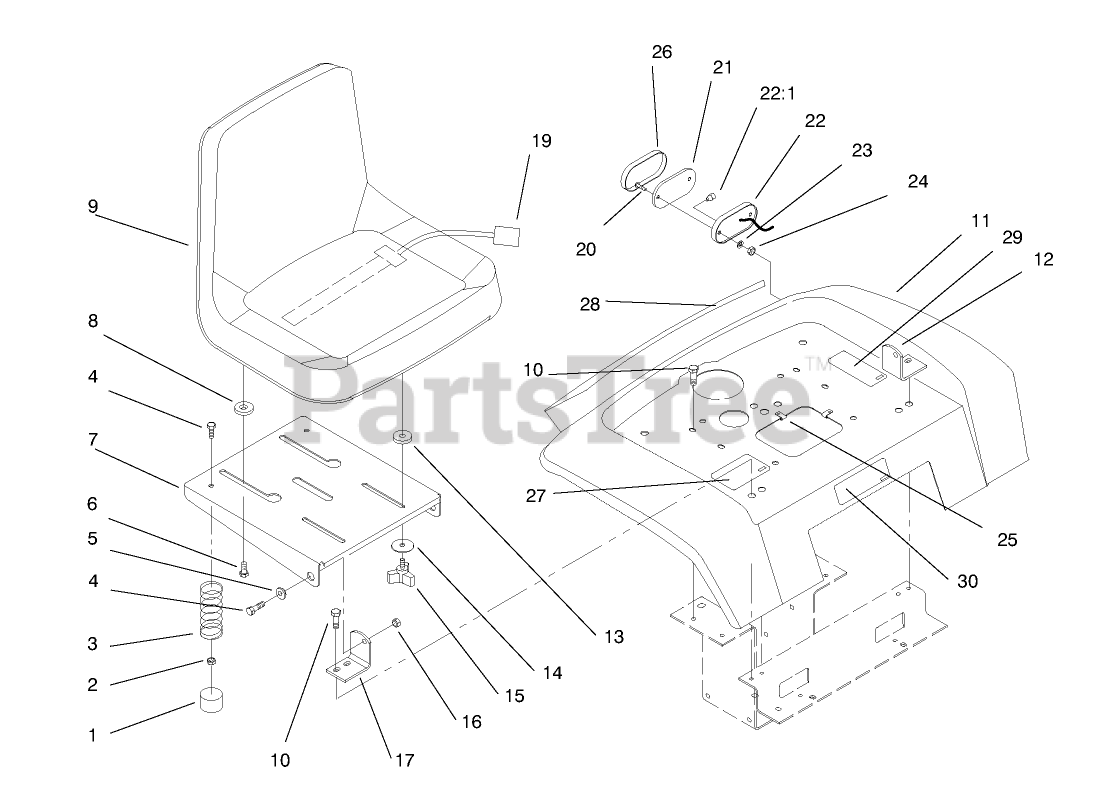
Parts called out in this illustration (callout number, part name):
1	CAP-PROTECTOR
2	NUT-LOCK, NI
3	SPRING-COMPRESSION
4	SCREW-HH
5	BUSHING
6	BOLT-SHOULDER
8	SPACER-NYLON
12	BRACKET-PIVOT, LH
13	SPACER-NYLON
14	WASHER
16	NUT-LOCK, NI
17	BRACKET-PIVOT, RH
19	SWITCH-SEAT
20	SCREW-PPH
23	WASHER-LOCK, INT
24	NUT-LOCK, NI
26	LENS-TAIL LIGHT
27	DECAL-DO NOT TOW
30	DECAL - USA
